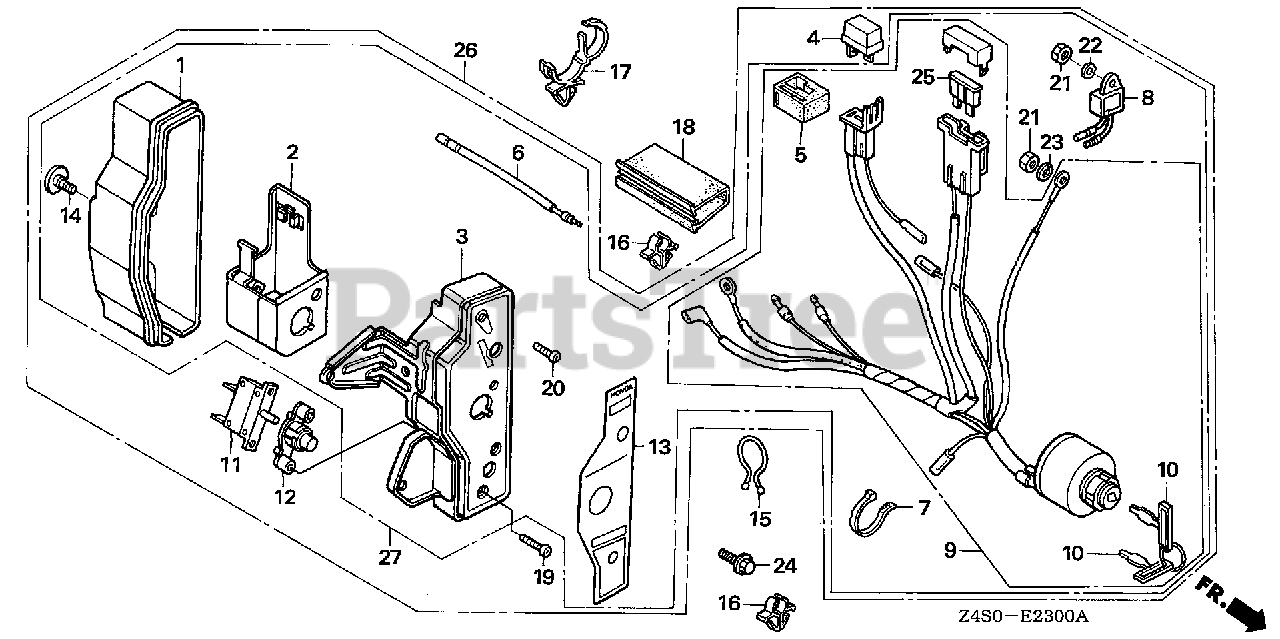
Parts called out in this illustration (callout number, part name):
1	CASE, CONTROL
2	BRACKET, CASE MOUNTING
3	PANEL, CONTROL *R280* (POWER RED)
6	SUB-WIRE HARNESS
8	ALERT UNIT, OIL
9	SWITCH ASSY., COMBINATION (10A CHG/RCM)
10	KEY (HONDALOCK)
13	MARK, CONTROL BOX (EXP)
14	SCREW, SPECIAL (6X12)
15	CLIP, PURSE LOCK
16	CLIP, CORD
17	STRAP, WIRE HARNESS (25MM) (BLACK)
18	TUBE, FASTENER (30MM)
20	SCREW, PAN (4X12)
21	NUT, HEX. (4MM) (SOURCE: VINTAGE PARTS INC.)
22	WASHER, PLAIN (4MM)
23	WASHER, SPRING (4MM)
24	BOLT, FLANGE (6X10)
25	FUSE, BLADE (15A)
27	BOX ASSY., CONTROL (EXP-ALERT/10A) *R280* (POWER RED)
